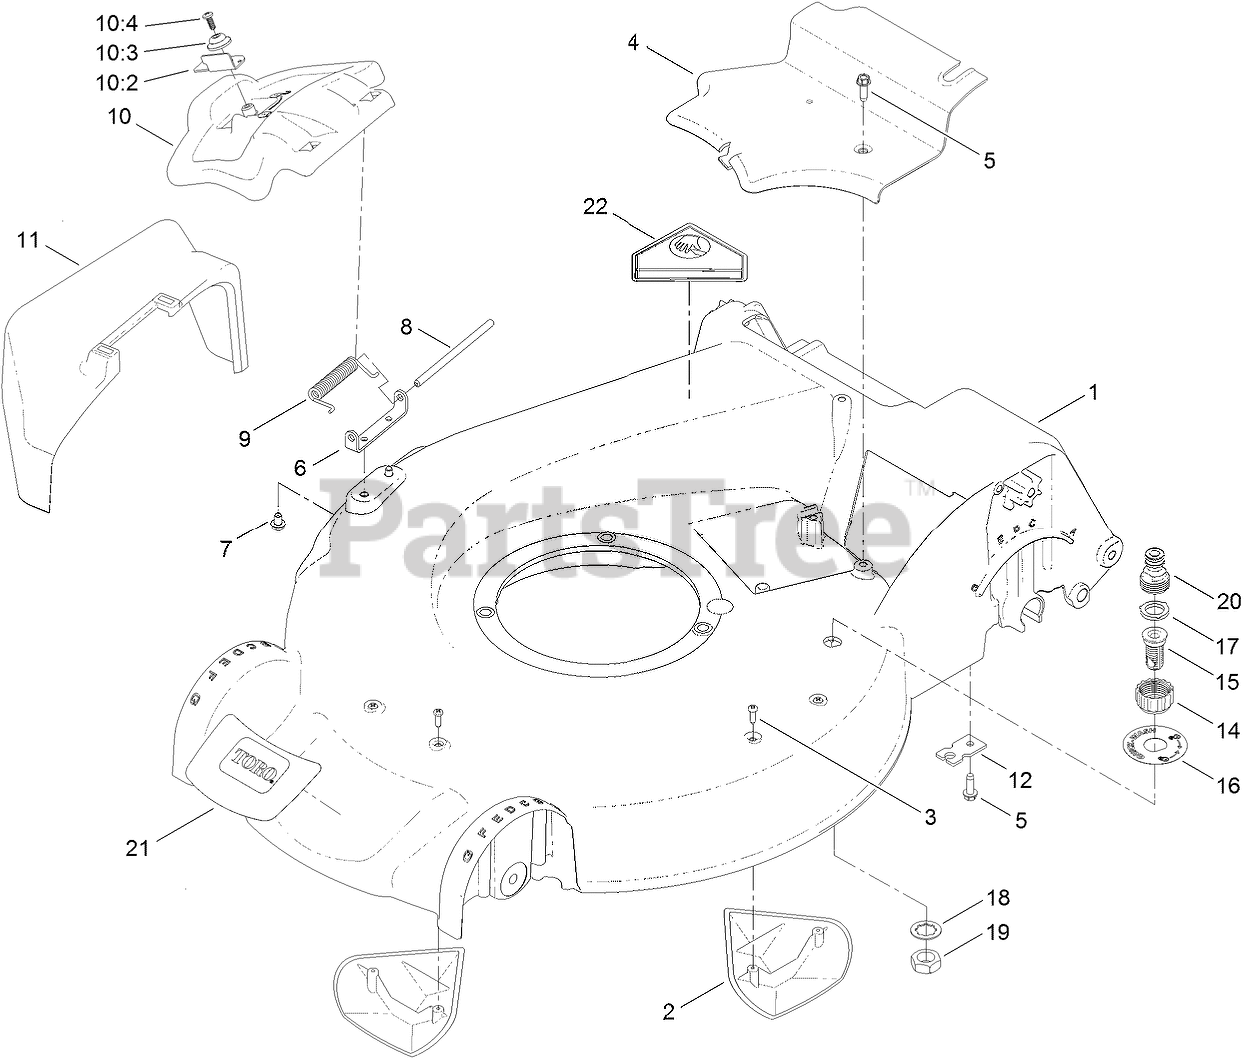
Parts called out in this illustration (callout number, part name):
1	HOUSING ASM
2	KICKER-HOUSING
3	SCREW-PPH
4	COVER-BELT
5	SCREW-HWHTF
6	BRACKET-COVER
7	SCREW-HWH
8	ROD-COVER
9	SPRING-TORSION
10	DISCHARGE DOOR ASM
10:2	LATCH-DOOR
10:3	CAP-DOOR
10:4	SCREW-PLASTITE
11	CHUTE-DISCHARGE, SIDE
12	BRACKET-CABLE, TRACTION
14	COUPLING-HOSE, WASHOUT PORT
15	PORT-WASHOUT
16	DECAL-PORT, WASHOUT
17	WASHER-SEAL, WASHOUT PORT
18	WASHER-TOOTH, INTERNAL
19	NUT-JAM
20	ADAPTER-CONNECT, QUICK
21	DECAL-DECK
22	DECAL-DANGER
